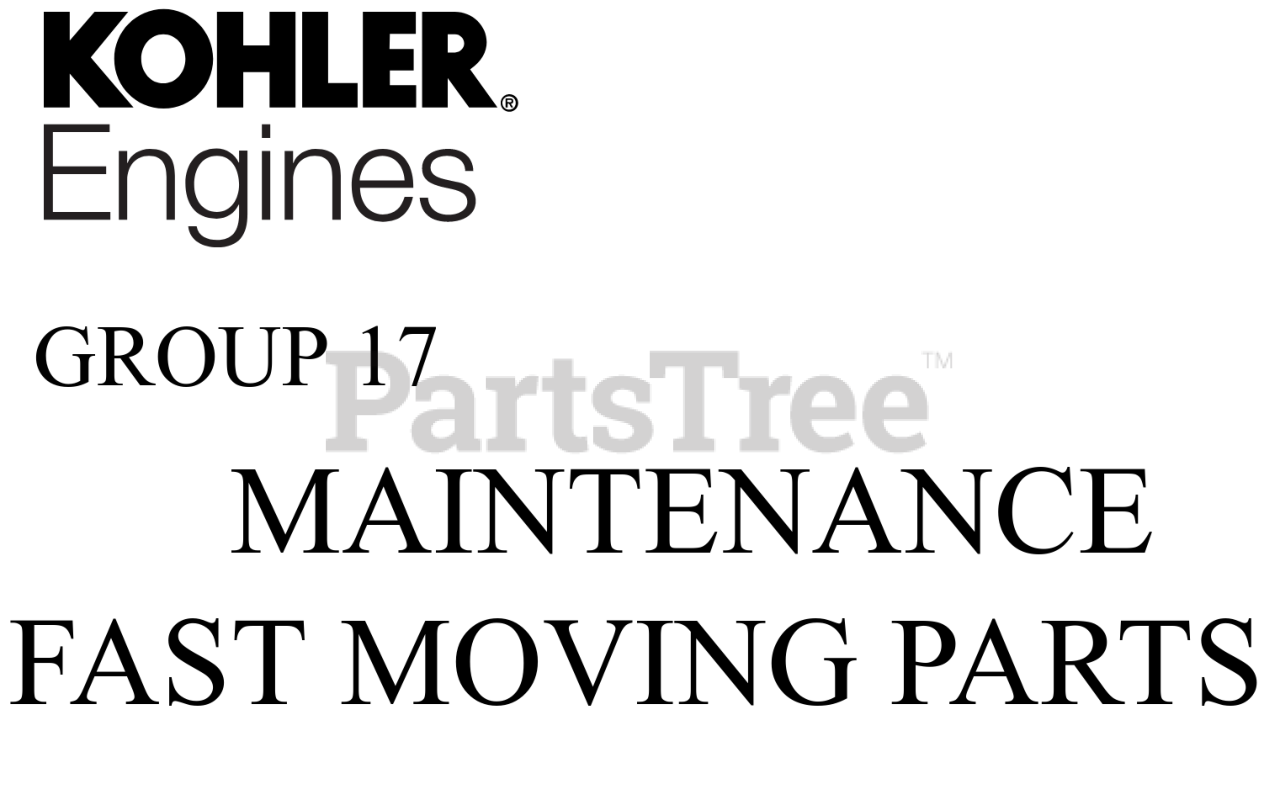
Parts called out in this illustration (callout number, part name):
NI	ELEMENT, AIR FILTER
NI	CONFIDANT MAINTENANCE KIT
NI	FILTER, FUEL
NI	PLUG, SPARK
NI	FILTER, BREATHER
NI	OIL FILTER
